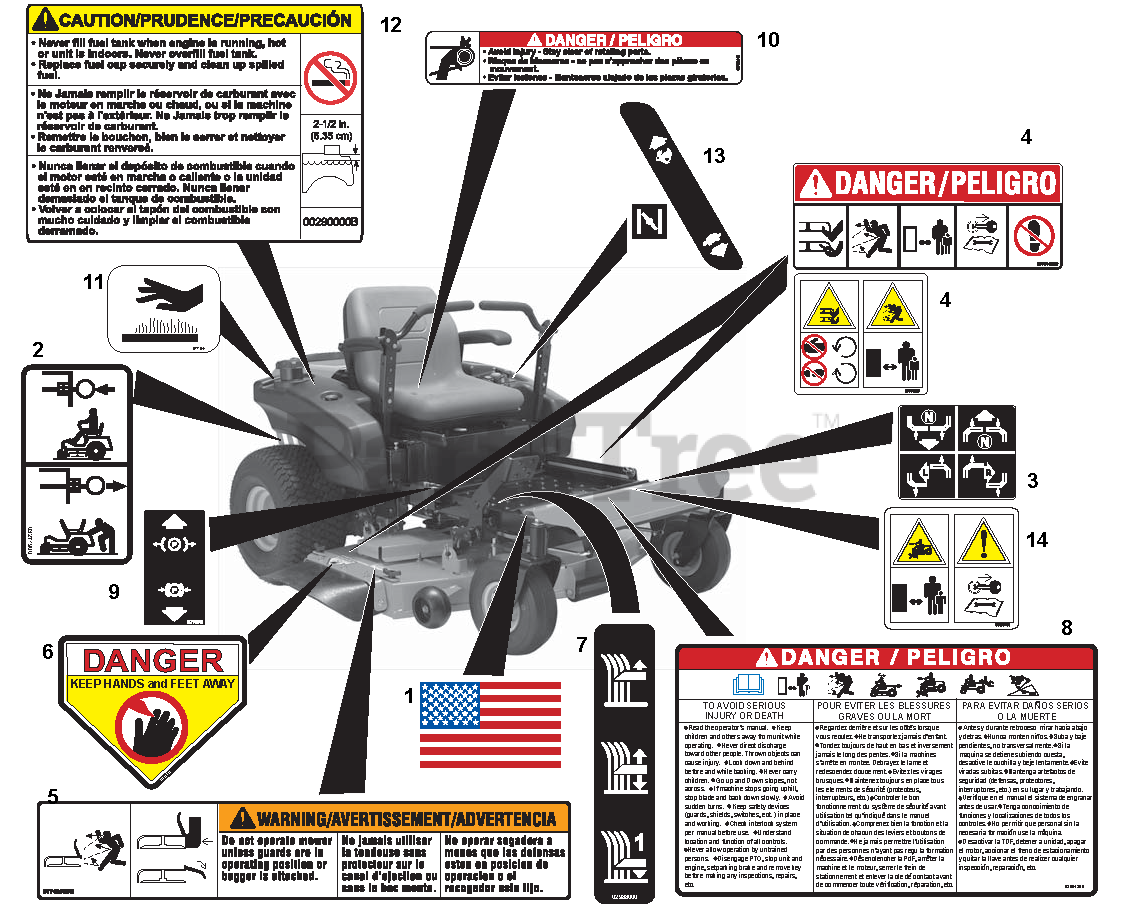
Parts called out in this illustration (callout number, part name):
1	DECAL, AMERICAN FLAG
2	DECAL, TRANSMISSION DISCONNECT
3	DECAL, INSTRUCTIONAL-STEERING
4	DECAL, MOWER PAN DANGER
5	DECAL, WARNING
6	DECAL, DANGER
7	DECAL, CUT HEIGHT
8	DECAL, DANGER BILINGUAL
9	DECAL, PARKING BRAKE LEVER
10	DECAL- DANGER
11	DECAL, HOT SURFACE
12	DECAL,FUEL WARNING
13	DECAL, SPEED CONTROL
14	DECAL, CE CAUTION
